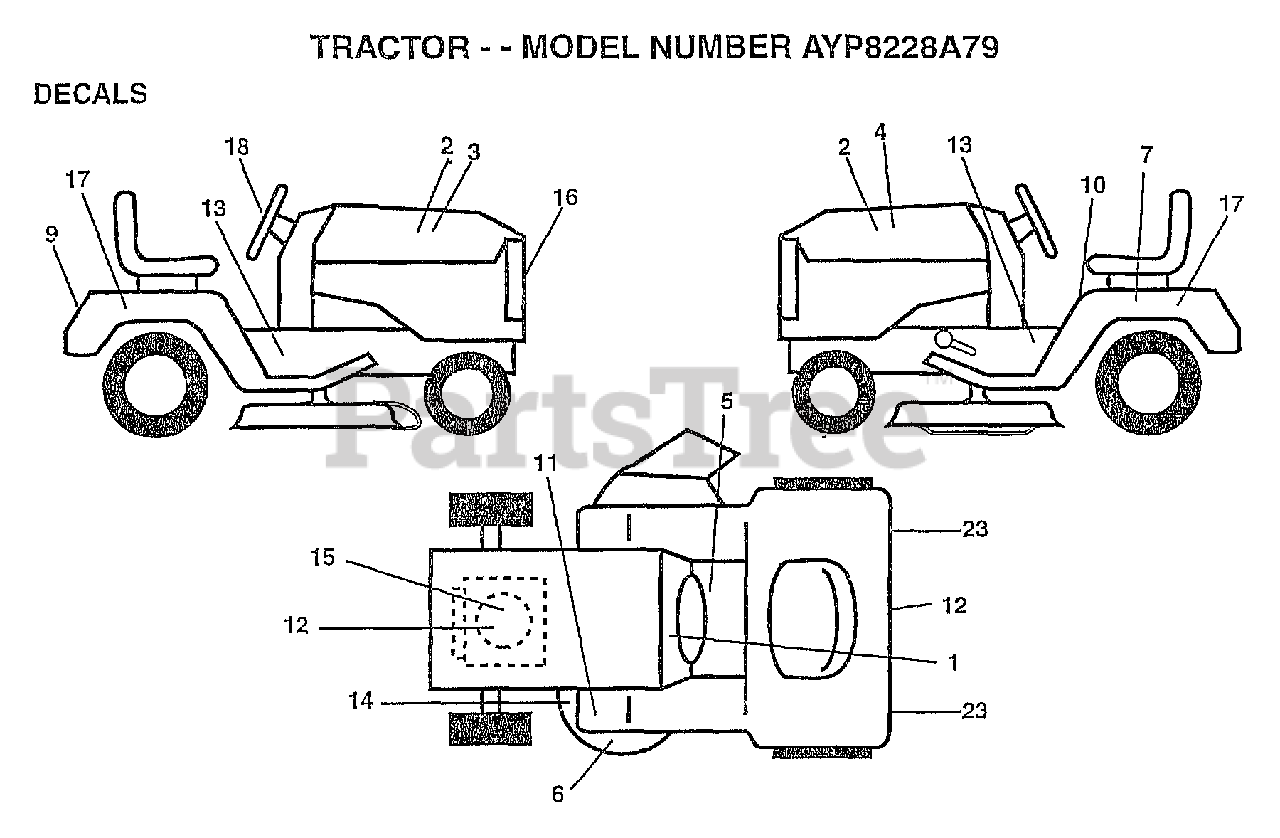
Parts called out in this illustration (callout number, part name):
1	"DECAL-INST,OPER"
2	NAMEPLATE.HD.WIZA
3	DECAL.HD.RH.WIZRD
4	DECAL.HD.LH.WIZRD
5	DECAL BRAK PARK
6	DECAL DECK WIZ +
7	DECAL.BATRY.3-3908
10	"DECAL DANGER,FEND"
12	DECAL D-BAR CNTRL
13	DECAL CHASSIS 50
14	"DECAL.V.BELT.44"""
15	DECAL.PNL.SD.KOHL
16	DECAL.GRILLE.WIZ+
17	DECAL.FENDER.WIZ
18	DECAL INS STG WHL
23	REFLECTOR-TAIL YT
